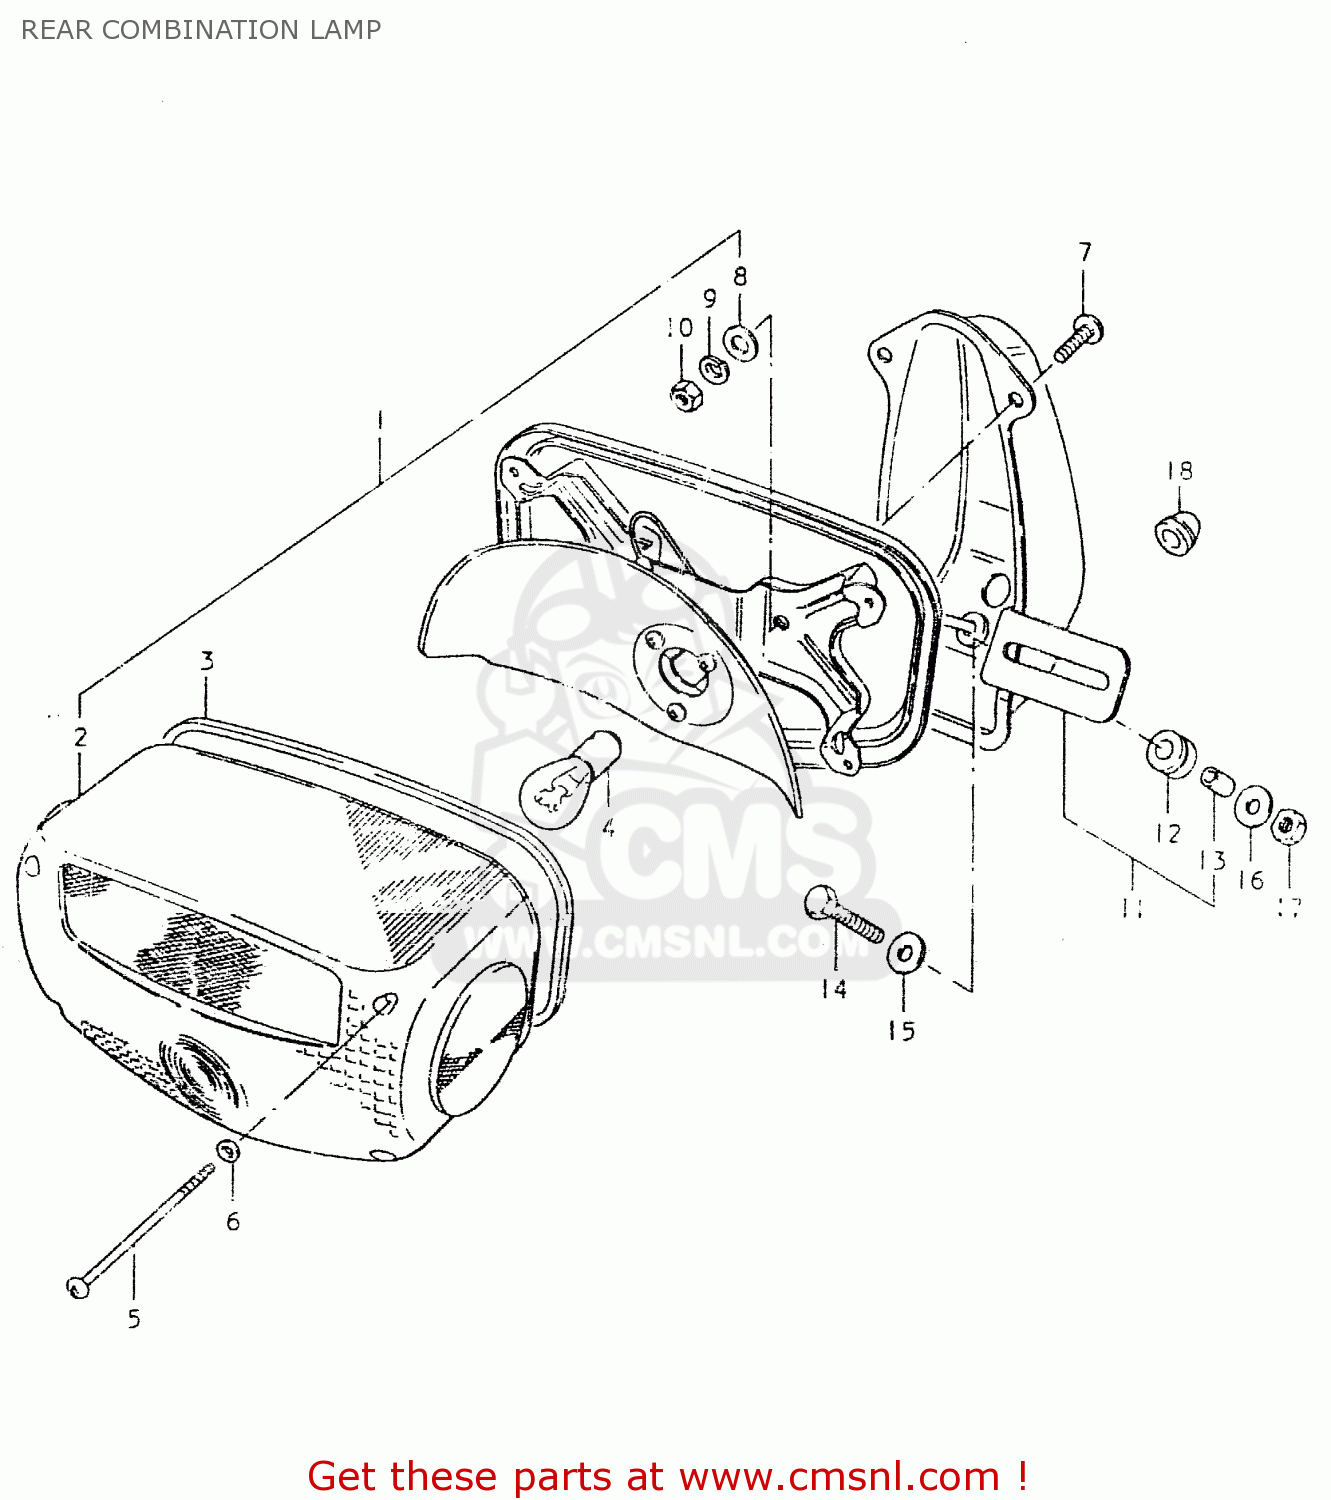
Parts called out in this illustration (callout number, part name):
1	LAMP UNIT,REAR COMBINATION
2	LENS,REAR COMBINATION LAMP
3	GASKET (NAS)
4	BULB(12V23W)
5	SCREW (4X55)
6	GASKET (NAS)
7	SCREW 6X12
8	WASHER
9	LOCK WASHER
10	NUT
11	BRACKET UNIT,TAIL LAMP
12	CUSHION
13	SPACER,REAR COMBINATION LAMP
14	BOLT
15	WASHER (6.5X20X1.2)
16	WASHER
17	NUT
18	GROMMET
